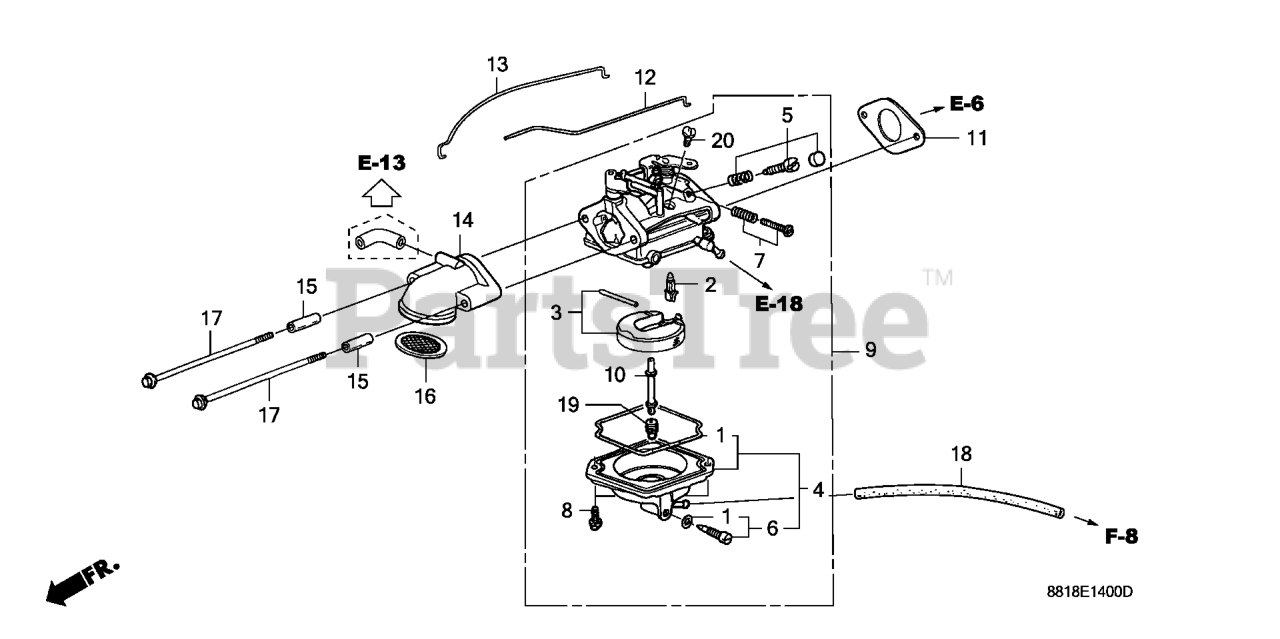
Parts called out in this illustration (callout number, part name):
1	GASKET SET
2	VALVE SET, FLOAT
3	FLOAT SET
4	CHAMBER SET, FLOAT
5	SCREW SET (CARBURETOR NO.)
6	SCREW SET, DRAIN (CARBURETOR NO.)
7	SCREW SET
7	SCREW SET B
8	SCREW, PAN
9	CARBURETOR ASSY. (BC01G B)
10	NOZZLE, MAIN
11	GASKET, CARBURETOR
12	ROD, THROTTLE
13	ROD, CHOKE
14	GUIDE, AIR
15	COLLAR, DISTANCE
16	TRAP, FLAME
17	BOLT, FLANGE (6X97)
18	BULK HOSE, VINYL (3.5X6.5X8000) (9500(95003-05001-60M) (CARBURETOR NO.)
19	JET, MAIN (#82)
19	JET, MAIN (#85) Use up to Engine SN BE81B B.
19	JET, MAIN (#88) Use up to Engine SN BE81B B.
